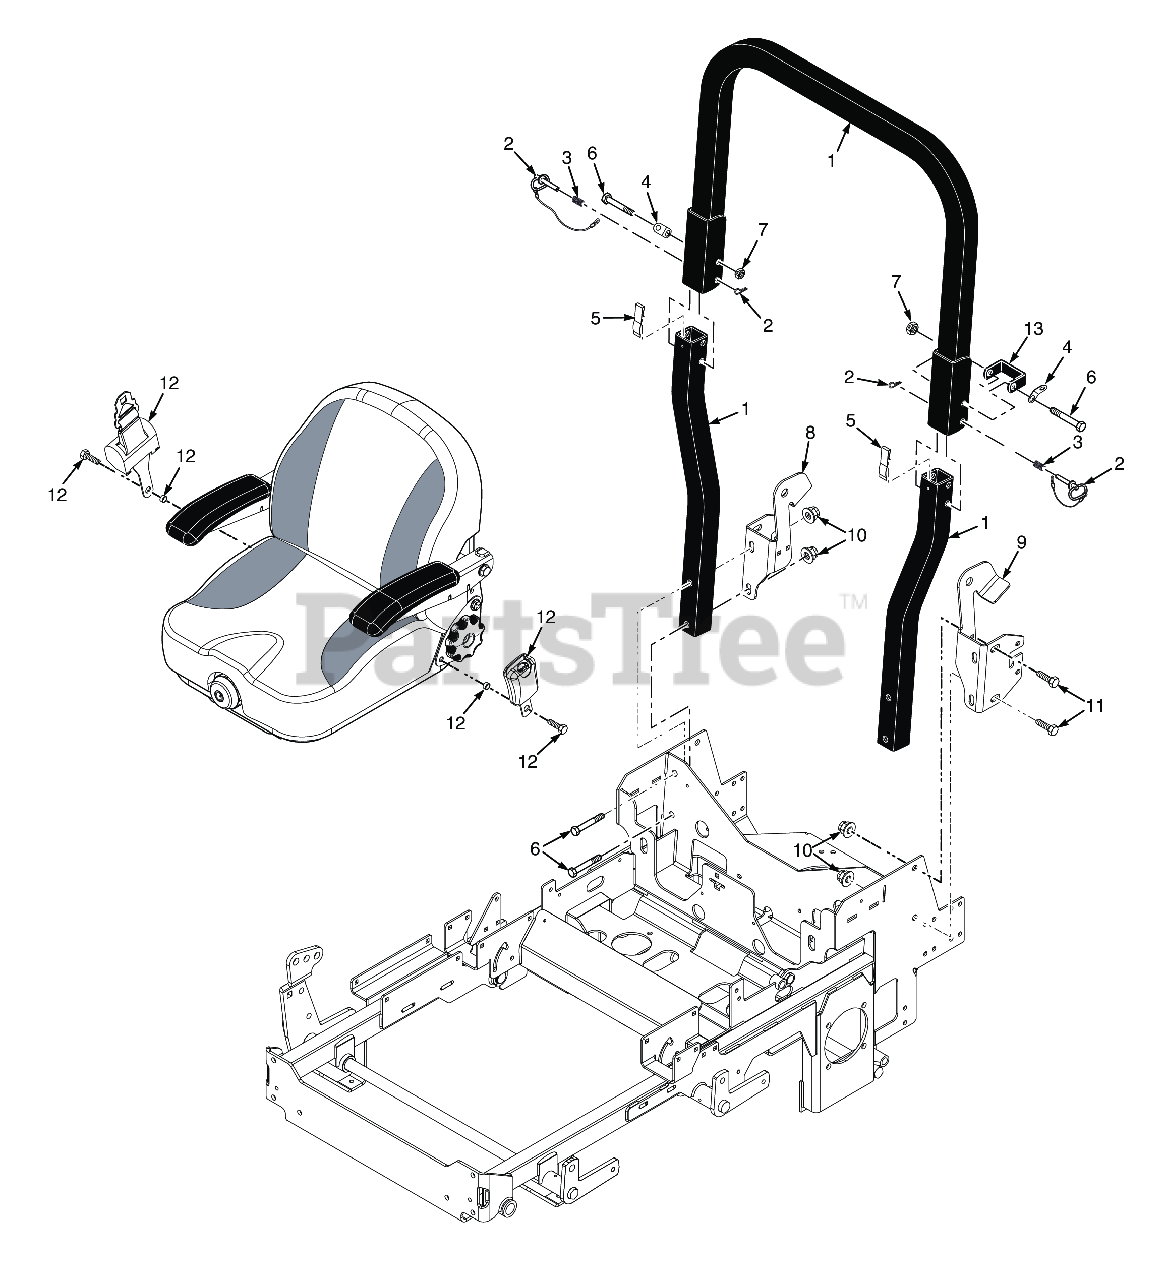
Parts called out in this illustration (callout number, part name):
1	ROPS Assembly, Foldable
1	ROPS ASSY, FOLDABLE
2	Pin Assembly, ROPS Hinge
3	Spring, ROPS
4	Clip, ROPS
5	Spring, ROPS Anti-Rattle
6	Bolt, Hex Head, 1/2-13 x 3-1/4"
7	Locknut, Hex 1/2-13 Center Lock
8	ROPS Mount, RH
8	ROPS Mount, RH, 29CV-EFI
9	ROPS Mount, LH
9	ROPS Mount, LH, 29CV-EFI
10	Nut, Elastic Stop 1/2-13, (STT-52 & STTII-52)
11	Bolt, Hex Head 1/2-13 x 1-1/4"
12	Seat Belt Kit (Suspension Seat)
12	Seat Belt Kit (Soft Ride Seat)
13	STOP, ROPS
